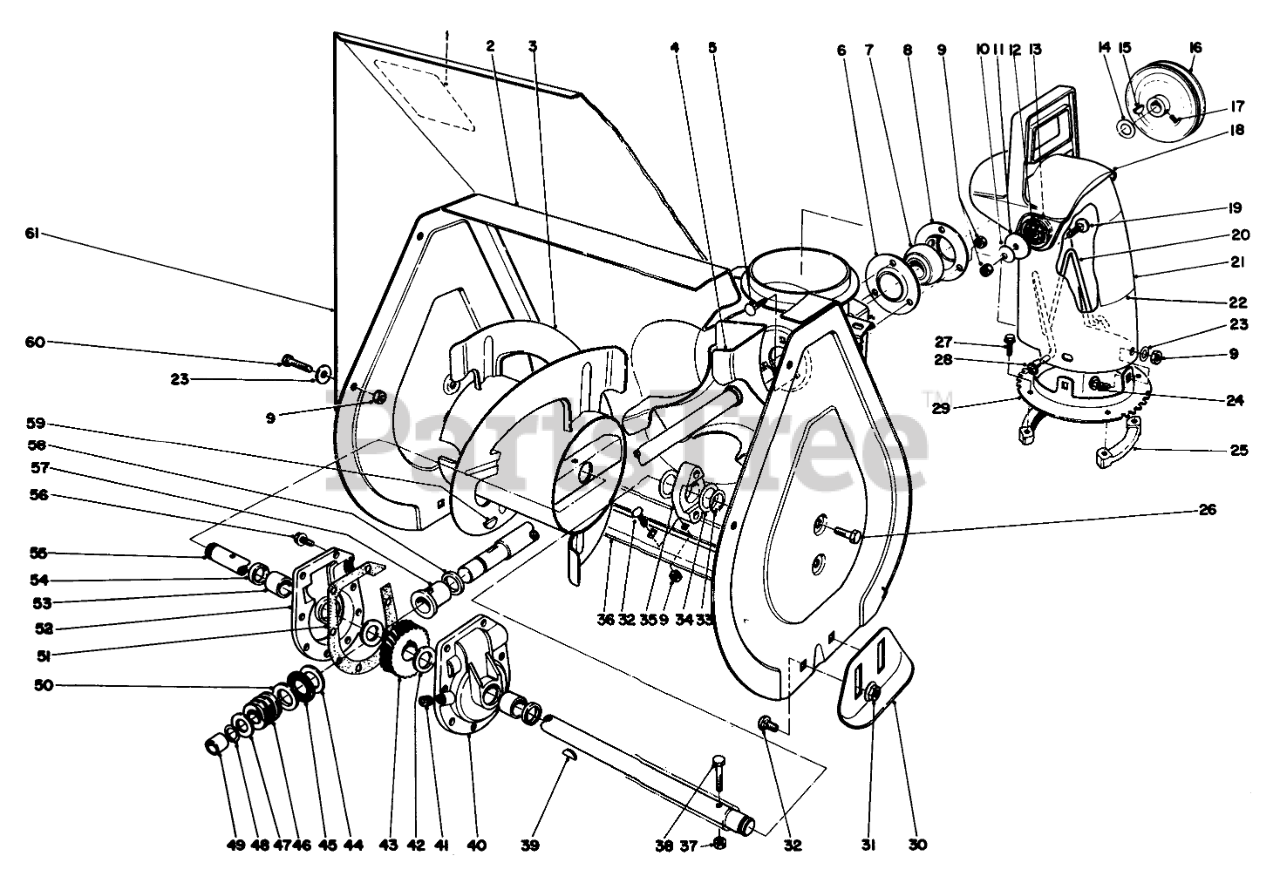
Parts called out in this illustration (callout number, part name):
1	DECAL-WARNING, AUGER
2	Housing-Auger (Incl. Ref. #1)
3	Auger R.H.
4	Shaft & Impeiler
5	BOLT-CARR
6	FLANGE-CUP, BEARING
7	Ball Bearing
8	FLANGE-CUP, BEARING
9	NUT-LOCK, NI
10	WASHER-BELLEVILLE
11	WASHER-FLAT
12	PLATE-FRICTION
13	WASHER-RUBBER
14	WASHER
15	KEY-WOODRUFF
16	PULLEY
17	SCREW-SET, SQH
18	CHUTE-DEFLECTOR
19	SCREW-CARR
20	WIRE-CHUTE
21	Chute-Discharge
22	Decal-Danger
23	WASHER-PLAIN
24	SCREW-CARR
25	RING-CHUTE, RETAINER
26	SCREW-HWHTF
27	SCREW-SPECIAL
28	NUT-PUSH
29	Chute Ring
30	Skid
31	NUT-HF
32	BOLT-CARR
33	RING-RETAINING
34	WASHER
35	BEARING-AUGER
36	Blade-Scraper
37	NUT-LOCK, CONE
38	SCREW-HH
39	KEY-WOODRUFF
40	Gear Case L.H. (Incl. Ref. #53 & 54)
41	PLUG-PIPE, SQH
42	WASHER-THRUST
43	Gear
44	WASHER-THRUST
45	BEARING-THRUST
47	WASHER-THRUST
48	Ring-Snap
49	BUSHING
50	WASHER-THRUST
51	GASKET-CASE, GEAR
52	Gear Case R.H. (Incl. Ref. #53 & 54)
53	BUSHING
54	SEAL-OIL
55	AUGER SHAFT
56	SCREW-TAPTITE
57	BUSHING-INPUT
58	RING-QUAD
59	KEY-WOODRUFF
60	SCREW-HH
61	AUGER EXT 21 SCAND
